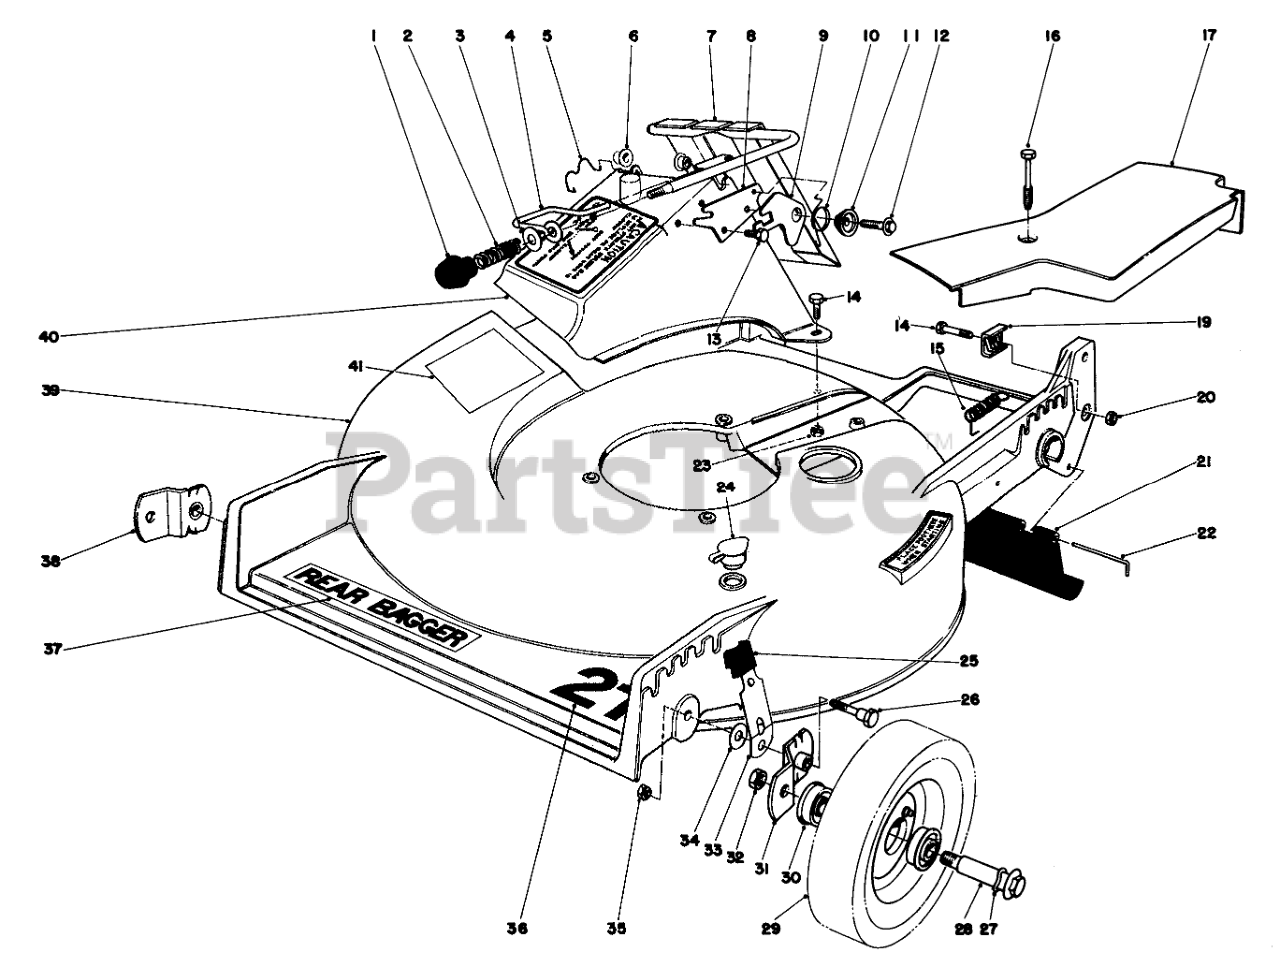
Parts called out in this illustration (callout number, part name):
2	COMPRESSION SPRING
3	WASHER
4	DOOR LATCH
5	DOOR RETAINER
6	BUSHING-NYLON
7	DOOR & HANDLE WA
8	DOOR LATCH PLATE
9	Latch Safety
10	TORSION SPRING
11	Latch Spacer
12	Screw
13	SCREW-HWH
14	SCREW-HH
15	IDLER SPRING
16	SCREW-HHFTF
17	Belt Cover
19	CLAMP-CABLE
20	NUT-JAM
21	SHIELD - TRAILING
22	Rod Shield
23	NUT-LOCK, NI
24	WASHOUT PLUG
25	KNOB-ARM
26	PIVOT SCREW
27	SPRING WASHER
29	Wheel & Tire Assembly (Incl. Ref. #30)
30	BEARING-BALL
31	PIVOT ARM ASM A
32	Nut
33	SPRING ARM ASM (R&S)
34	WASHER-PIVOT
35	Nut
36	Decal 21"
37	DECK DECAL
38	PIVOT ARM ASM B
39	Housing
40	DISCHARGE CHUTE B
41	Decal Caution (German)
